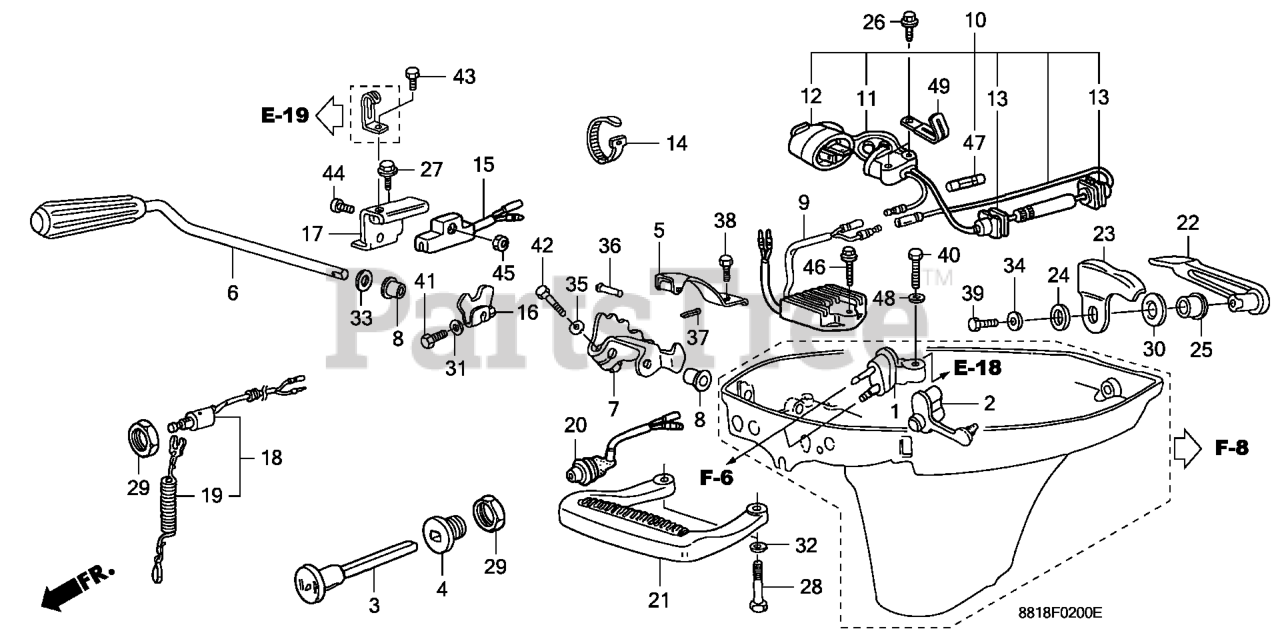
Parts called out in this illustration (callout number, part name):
1	CONNECTOR, FUEL *NH282MU* (OYSTER SILVER METALLIC-U)
2	CAP, FUEL JOINT
3	KNOB, CHOKE
4	GUIDE, CHOKE KNOB
5	SPRING, CLICK
6	SHAFT, SHIFT
7	ARM, GEARSHIFT
8	BUSH, SHAFT
9	RECTIFIER ASSY., REGULATOR
10	RECEPTACLE ASSY., CHARGE
11	RECEPTACLE
12	PLUG, RECEPTACLE
13	GROMMET, FUSE HOLDER
14	TIE, CABLE (NATURAL 2.4X92) Use up to Frame SN 1300359.
15	SWITCH ASSY., NEUTRAL
16	PLATE, SWITCH SHIELD
17	PLATE, SWITCH SETTING
18	SWITCH ASSY., EMERGENCY STOP
19	WIRE, EMERGENCY (SINGLE) (DUAL)
20	LAMP ASSY., INDICATOR
21	HANDLE, CARRYING *NH282MU* (OYSTER SILVER METALLIC-U)
22	LEVER, COVER LOCK *NH282MU* (OYSTER SILVER METALLIC-U)
23	HOOK, COVER LOCK
24	WASHER, COVER LOCK
25	BUSH, COVER LOCK
26	BOLT, FLANGE (5X22)
27	BOLT, FLANGE (6X12)
28	BOLT, HEX. (8X32)
29	NUT, HEX. (16MM) DUAL QTY = (2) (SINGLE)
30	SPRING, LEVER
31	WASHER, PLAIN (6MM) Use from Frame SN 4800713.
32	WASHER, PLAIN (8MM) Use up to Frame SN 4800712.
33	WASHER, PLAIN (10MM)
34	WASHER (6MM)
35	WASHER, PLAIN (8MM) Use from Frame SN 4800713.
36	PIN (5X17)
37	PIN, COTTER (1.6MM)
38	BOLT, FLANGE (6X12)
39	BOLT, FLANGE (6X16)
40	BOLT, FLANGE (6X20) (ENGINE NO.)
41	BOLT, HEX. (6X28)
42	BOLT, HEX. (8X28)
43	BOLT, HEX. (6X8)
44	SCREW, PAN (5X20)
45	NUT, HEX. (5MM)
46	BOLT, FLANGE (6X25)
47	FUSE A (5A)
49	CLIP B, CORD
